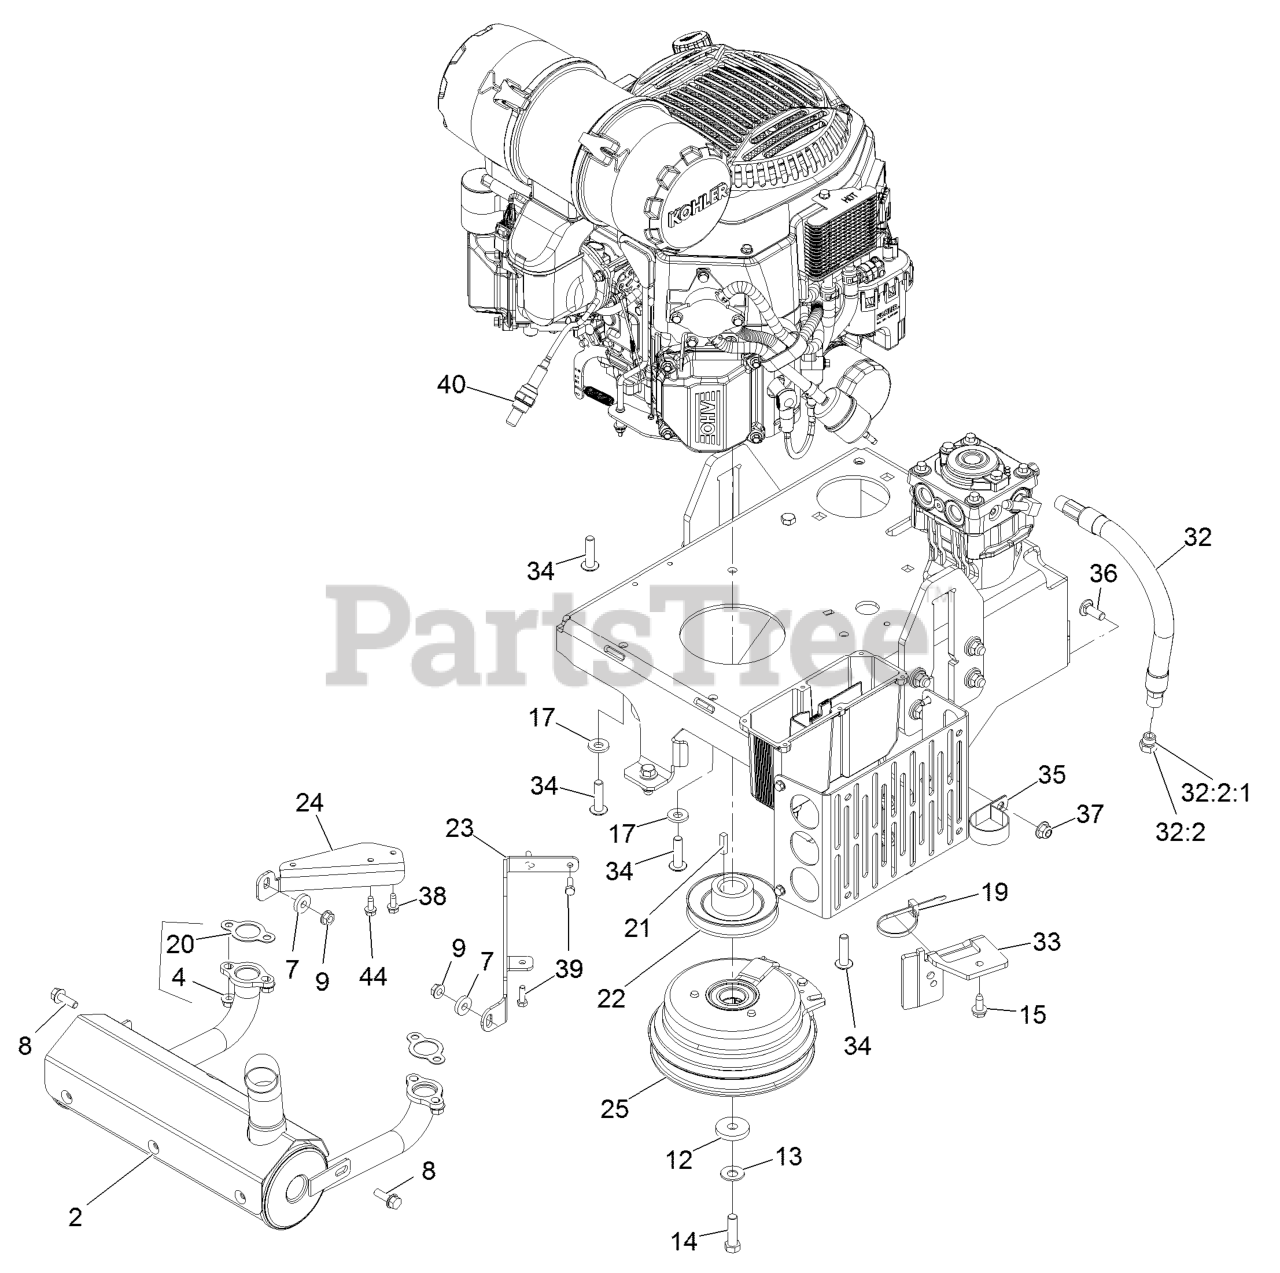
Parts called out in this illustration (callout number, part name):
4	NUT-FLANGE
8	SCREW-HHF
12	WASHER
13	WASHER-SPRING
14	SCREW-HH
15	Screw-HWH 5/16-18 X 3/4 Tf
17	WASHER-BELLEVILLE
19	TIE-CABLE
20	GASKET-EXHAUST
23	MOUNT, MUFFLER-LT
24	MOUNT, MUFFLER-RT
25	CLUTCH-200 FT-LB, 1.125 B
32	OIL DRAIN HOSE ASM
32:2	PLUG-HH
32:2:1	O-RING
33	BRACKET-ANCHOR, CLUTCH
34	SCREW-BHTF
35	CLAMP-R
36	SCREW-CARR
37	NUT-HF, NI
38	SCREW-HWHTF
39	SCREW-HH M6-1 X 20Mm W/Patch
40	SENSOR-OXYGEN
44	SCREW-HWHTF
